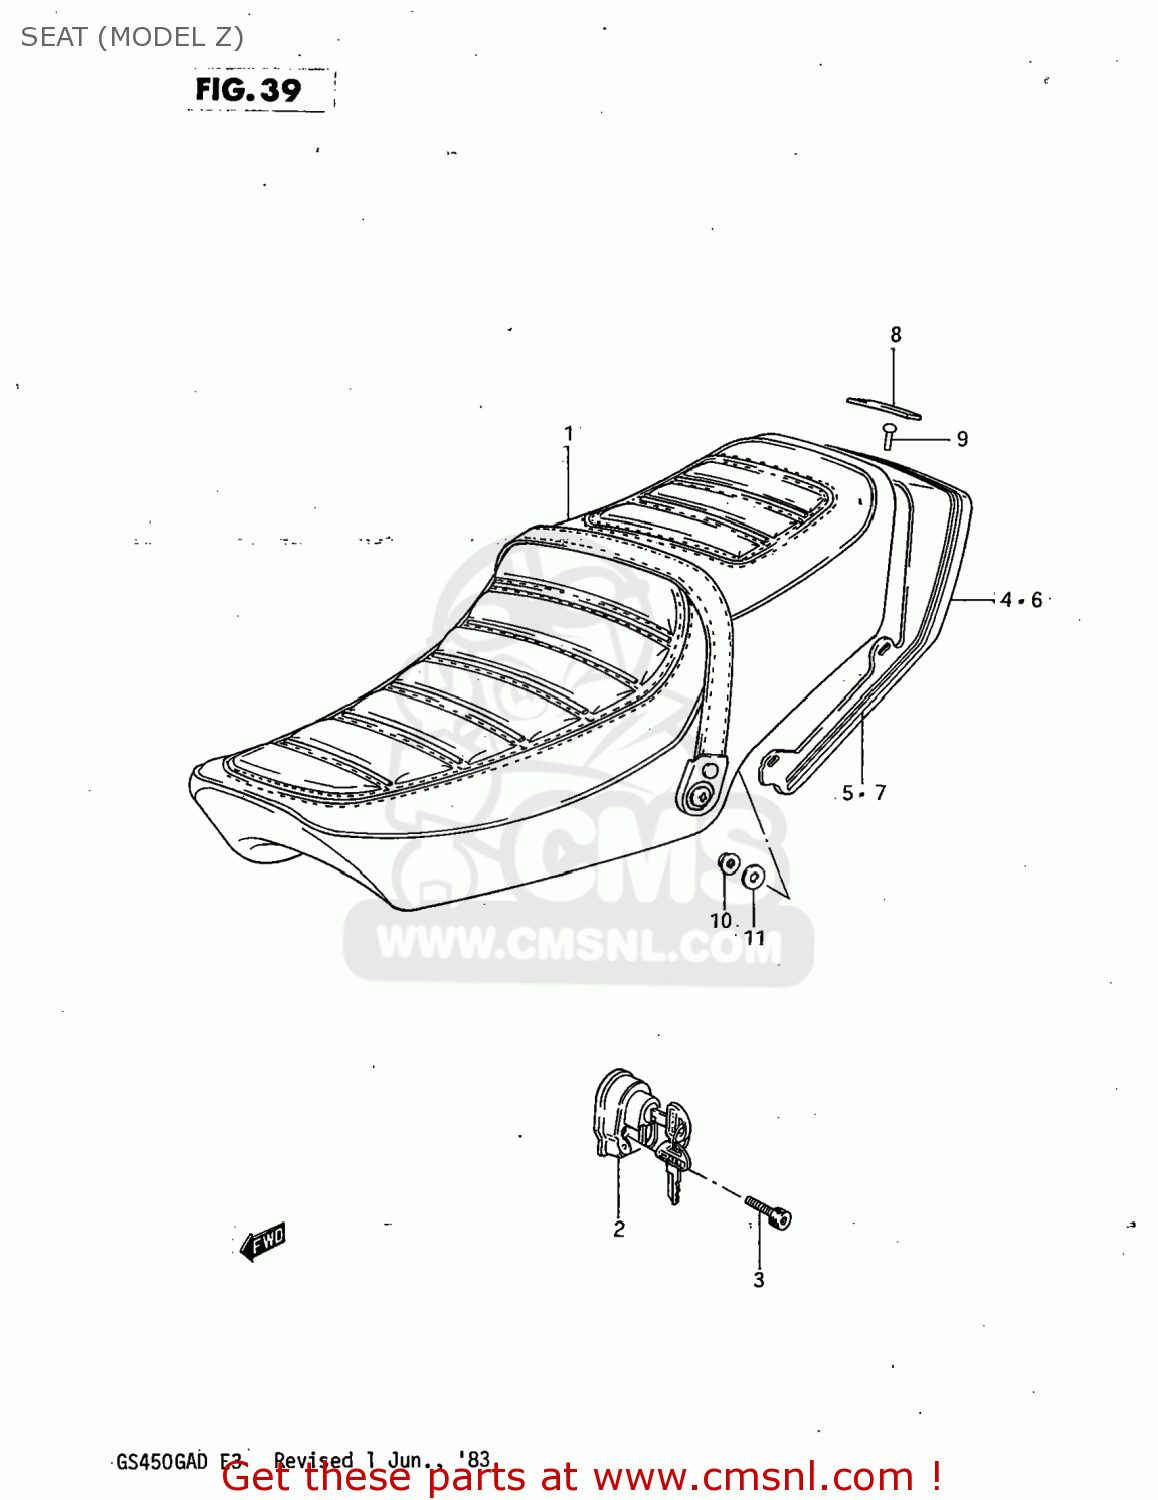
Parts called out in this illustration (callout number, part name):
1	SEAT ASSEMBLY
2	LOCK ASSY,HELMET
3	BOLT 5X25
4	COVER,SEAT TAIL
5	TAPE SET,SEAT TAIL COVER
6	COVER,SEAT TAIL
7	TAPE SET,SEAT TAIL COVER
8	EMBLEM
9	RIVET
10	NUT
11	WASHER (6.7X16X1.8)
